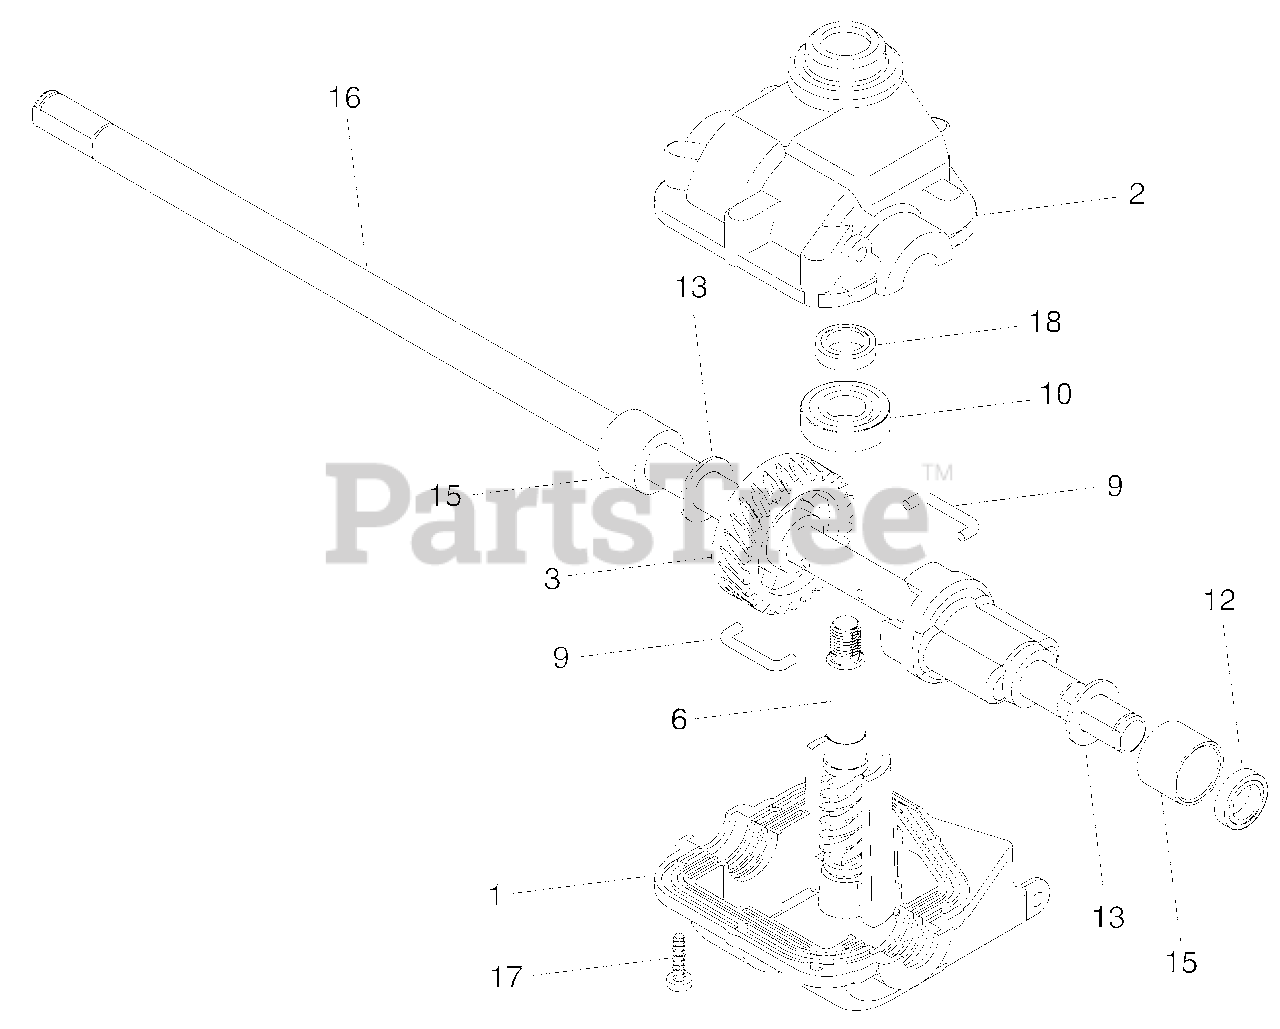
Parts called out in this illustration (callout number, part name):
1	Case, Lower
2	Case, Upper
3	Gear, 24 Teeth
6	Shaft, Input
9	Wire, Formed
10	Bearing, Ball
12	Seal, Output Shaft
16	Shaft, Output
18	Seal, Input Shaft
